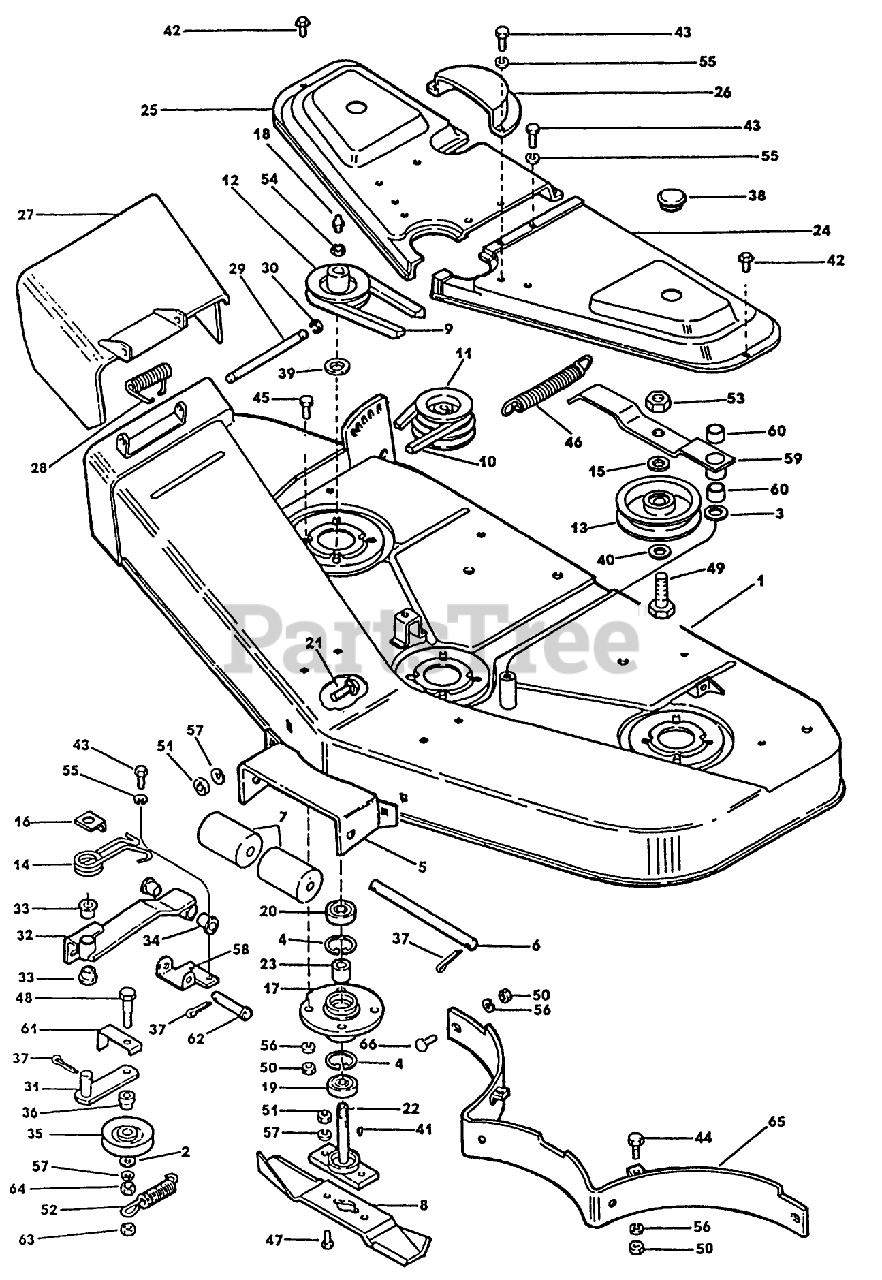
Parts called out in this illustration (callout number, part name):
2	WASHER
6	SHAFT
7	ROLLER
9	V-BELT
10	V-BELT (DRIVE)
13	PULLEY - IDLER
14	SPRING
17	HOUSING-SPINDLE S
22	SPINDLE ASSEMBLY
28	SPRING - CHUTE
29	SHAFT - CHUTE
30	E-RING
32	PIVOT ASSEMBLY
33	BUSHING
34	BUSHING
35	PULLEY - V-IDLER
36	SPACER
38	PLUG - BELT COVER
39	SPACER
42	SCREW-THREAD FRMG
43	SCREW-HH
44	SCREW - HEX
45	SCREW
46	SPRING
48	SCREW-HH
50	NUT SS
51	NUT
52	SPRING - TENSION *B
54	LOCKNUT-SPECIAL
57	WASHER
60	BEARING-SLEEVE
61	GUIDE - BELT
62	PIN - CLEVIS
63	NUT
64	NUT-HEX JAM
